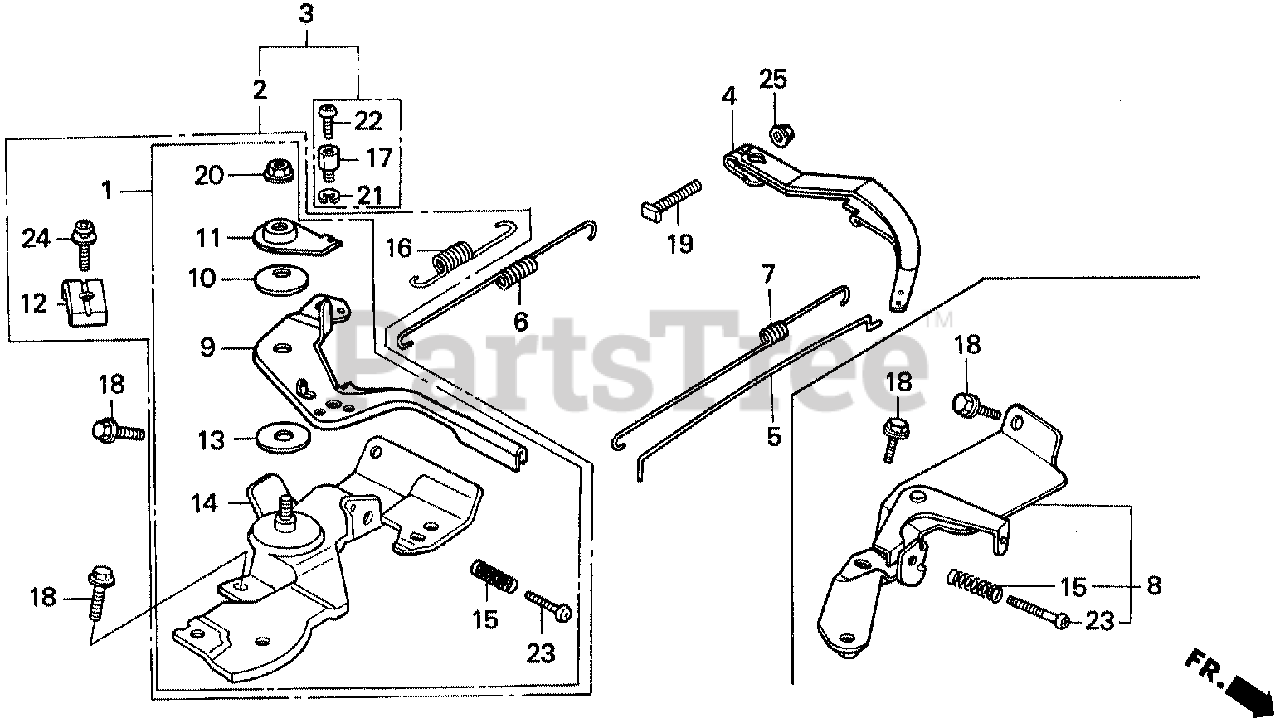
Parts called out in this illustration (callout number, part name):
2	CONTROL ASSY. (REMOTE)
4	ARM, GOVERNOR
5	ROD, GOVERNOR
6	SPRING, GOVERNOR
7	SPRING, THROTTLE RETURN
9	LEVER, CONTROL
10	SPRING, LEVER
11	WASHER, CONTROL LEVER
12	HOLDER, CABLE
13	SPACER, CONTROL LEVER
14	BASE, CONTROL
14	BASE, CONTROL (REMOTE)
15	SPRING, CONTROL ADJUSTING
16	SPRING, CABLE RETURN
18	BOLT, FLANGE (6X12) (CT200)
18	BOLT, FLANGE (6X13)
19	BOLT, GOVERNOR ARM
20	NUT, SELF-LOCK (6MM)
23	SCREW, PAN (5X25)
24	SCREW, PAN (5X16)
24	SCREW-WASHER (5X16)
25	NUT, FLANGE (6MM)
